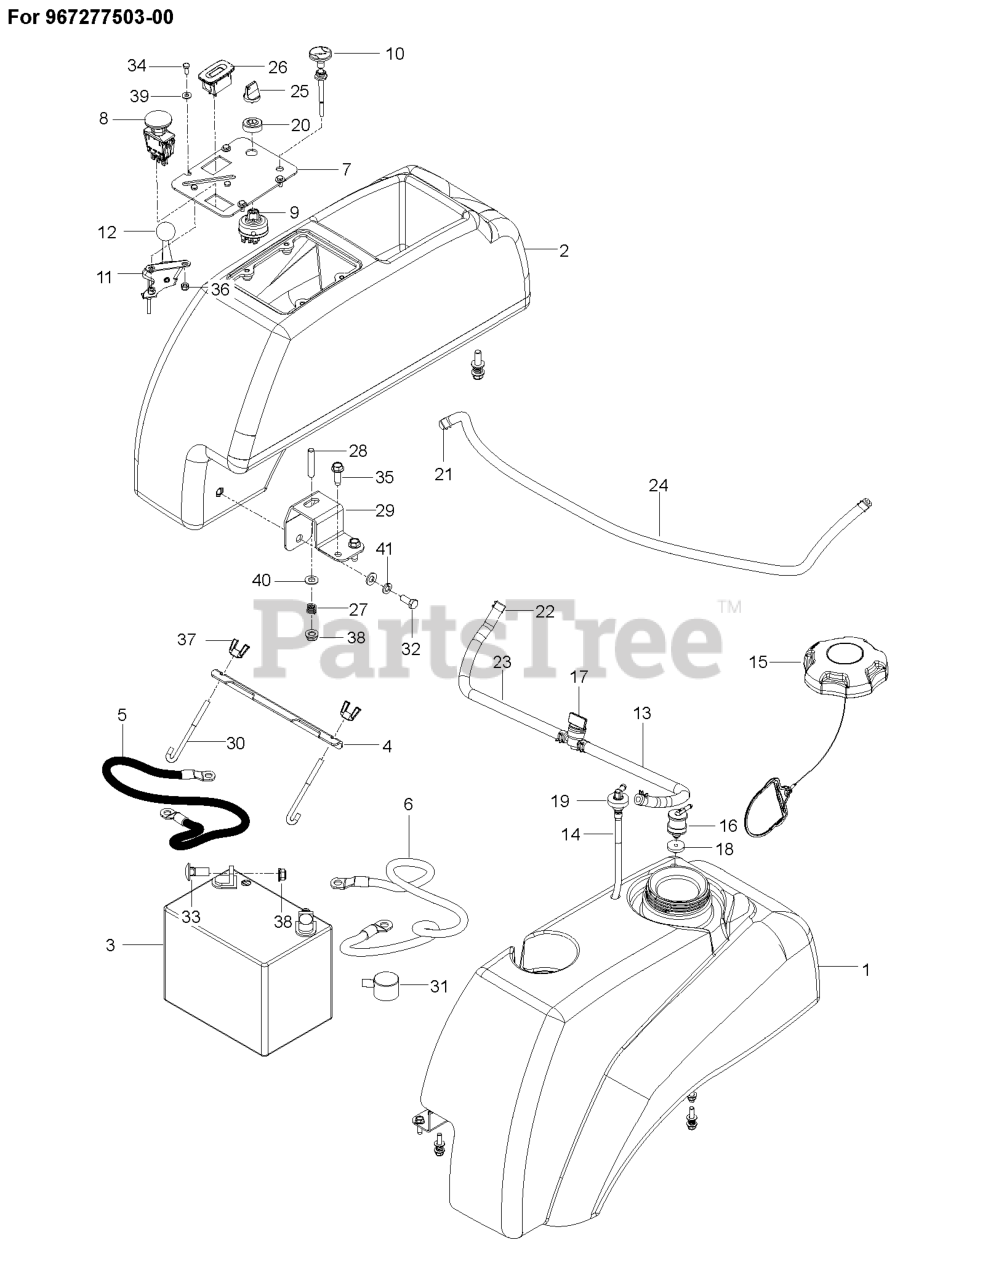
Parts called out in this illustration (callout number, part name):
1	FUEL TANK ASSY MZ
2	FENDER CONSOLE
3	BATTERY, 12 V 330 AMP
4	BRACKET.BATTERY.MOUNT.PLATED
5	CABLE.GROUND.BATT.MZ.BLACK.39"
6	CABLE.BATT.SOLENOID.MZ.RED.25"
7	PLATE.CONSOLE.BLACK
8	RP SWITCH.PTO.TERMINAL.STD.RED
9	SWITCH, IGNITION, INDAK
10	CHOKE CABLE
11	THROTTLE CABLE
12	KNOB.ROUND.BALL.BLACK
13	FUEL.HOSE.SHUT.OFF.ASM.10".10"
14	FITTING, FUEL
15	CAP, FUEL
16	VALVE.FUEL.CHECK
17	FUEL VALVE
18	GROMMET, CHECK VALVE
19	RUBBER GROMMET
20	CAP IGNITION NUT
21	CLAMP, HOSE
22	HOSE CLAMP
23	HOSE.1/4".LOW.PERM.FUEL.LN.10"
24	HOSE.3/16".VAPOR.LINE.39"LGTH
25	KEY, IGNITION
26	GUAGE.SRVCMNDR.HRMTR.
28	STUD, 5/16C
29	SUPPORT.PNT.TANK.FRONT.STAMPED
31	COVER.TERMINAL.BATTERY
32	HCS 5/16C X 3/4
33	BOLT 5/16C X 3/4" CARRIAGE
34	HCS #10-24 X 1/2
35	SCREW
36	NUT 10-24 NYLOC
37	WING NUT 1/4
38	5/16-18 NYLOC FLANGE NUT
40	WASHER
41	WASHER.LOCK.HVY.HLCL.SPR.5/16
